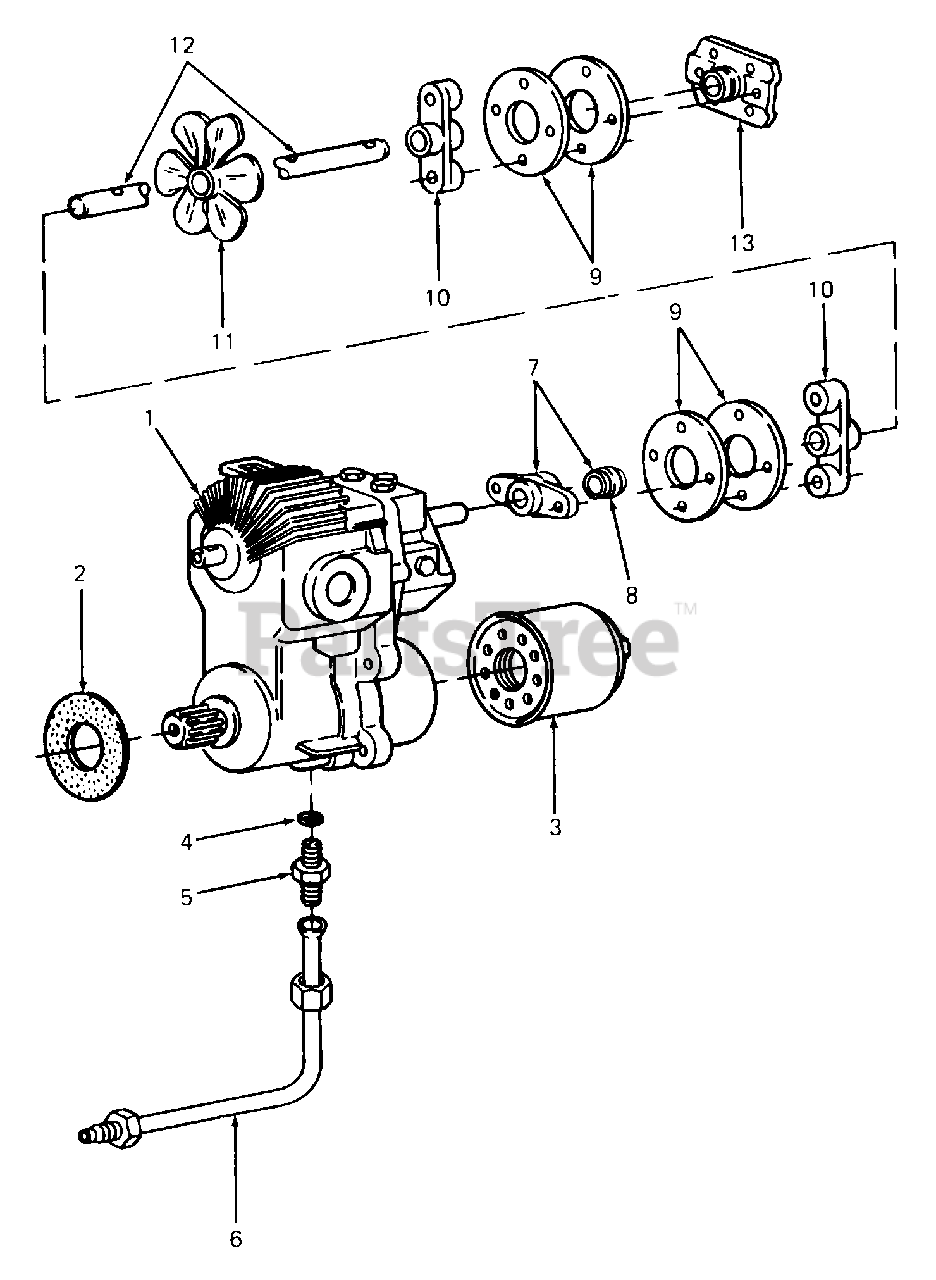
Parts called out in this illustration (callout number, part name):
1	Pump, Hydrostatic
2	Gasket, Front
3	Filter, Oil
4	O-Ring, 5/8 OD Tube
5	Connector, 37 Degree
6	Tube Assy
7	Coupling Assy
8	Bushing, Ball
9	Disc, Flexible
10	Arm, Coupling
11	Fan, Cooling
12	Shaft, Drive
13	Flange Assy, Drive Shaft
